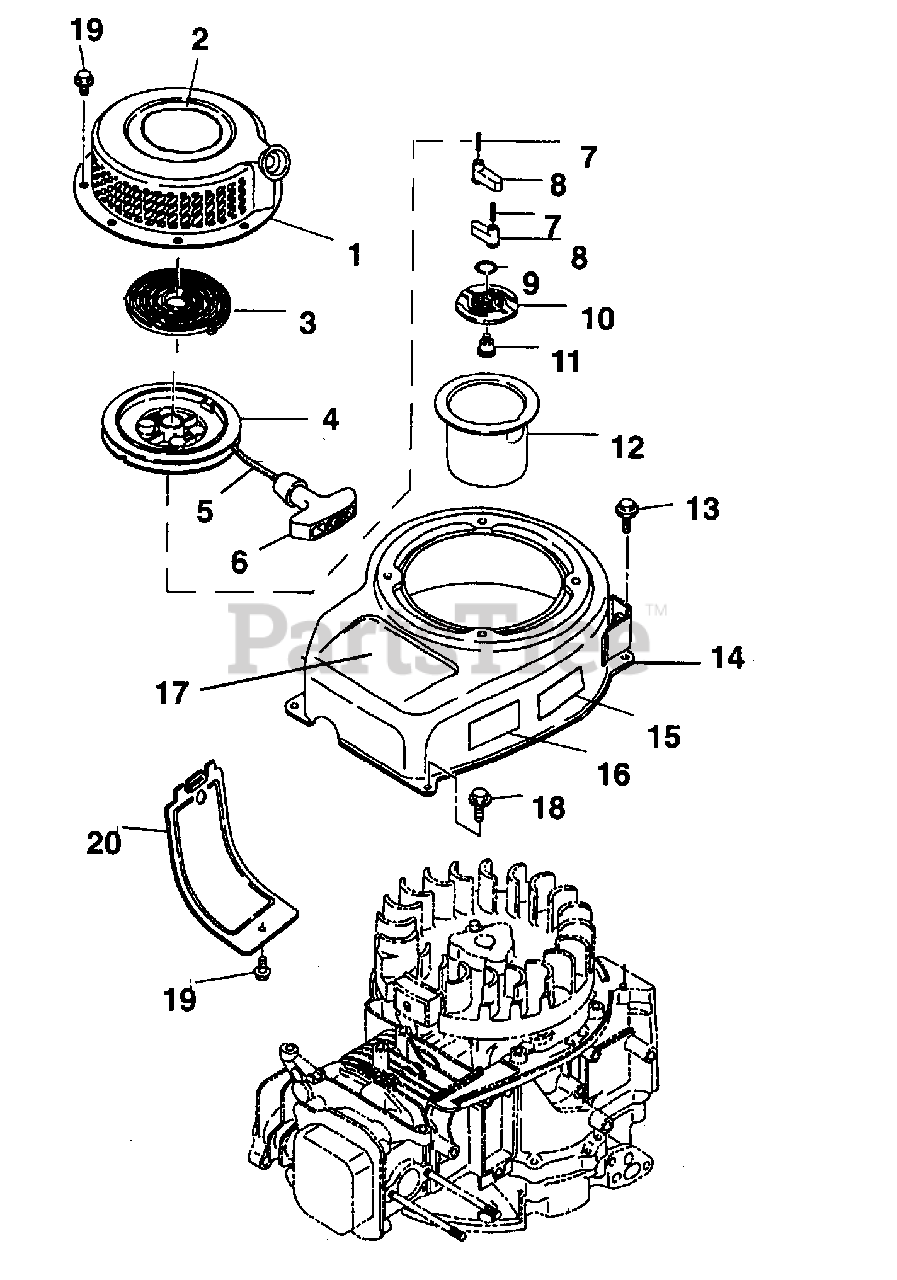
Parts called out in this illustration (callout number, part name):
1	RECOIL STARTER Compl
3	SPRING, Spiral
5	ROPE, Starter
6	KNOB, Starter
7	SPRING, Return
9	SPRING, Friction
10	GUIDE, Ratchet
11	SCREW, Set
12	PULLEY, Starter
13	BOLT, Flange
14	BLOWER HOUSING
15	LABEL, Warning
16	LABEL, Emission Control
18	BOLT, Flange
19	BOLT, Flange
20	BAFFLE, Cylinder
